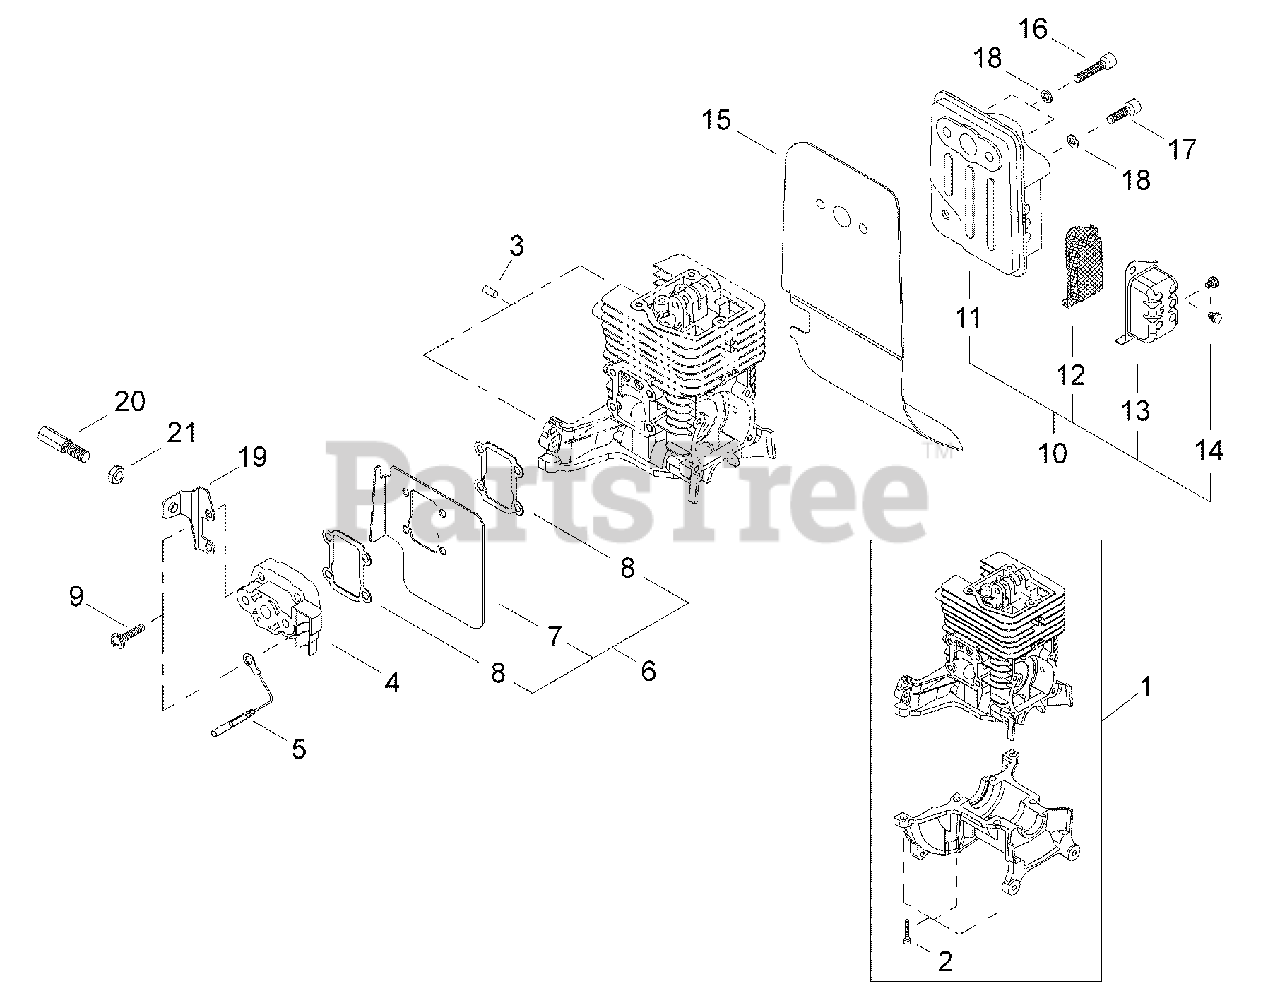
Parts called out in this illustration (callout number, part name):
1	CYLINDER BLOCK SET
2	SCREW - 5X16
3	PIN - LOCATING
4	INSULATOR
5	LEAD - GROUND
6	HEAT DEFLECTOR ASSY
7	DEFLECTOR, HEAT
8	SHIELD, INTAKE
9	SCREW - 5X22
10	MUFFLER ASSY
11	MUFFLER
12	SCREEN, SPARK ARRESTOR
13	GUIDE, EXHAUST
14	SCREW - 4X6
15	SHIELD, EXHAUST
16	SCREW - 5X25
17	SCREW - 5X16
18	WASHER - 5
19	BRACKET, THROTTLE CABLE
20	NUT, CABLE ADJUST
21	LOCKNUT - 6
